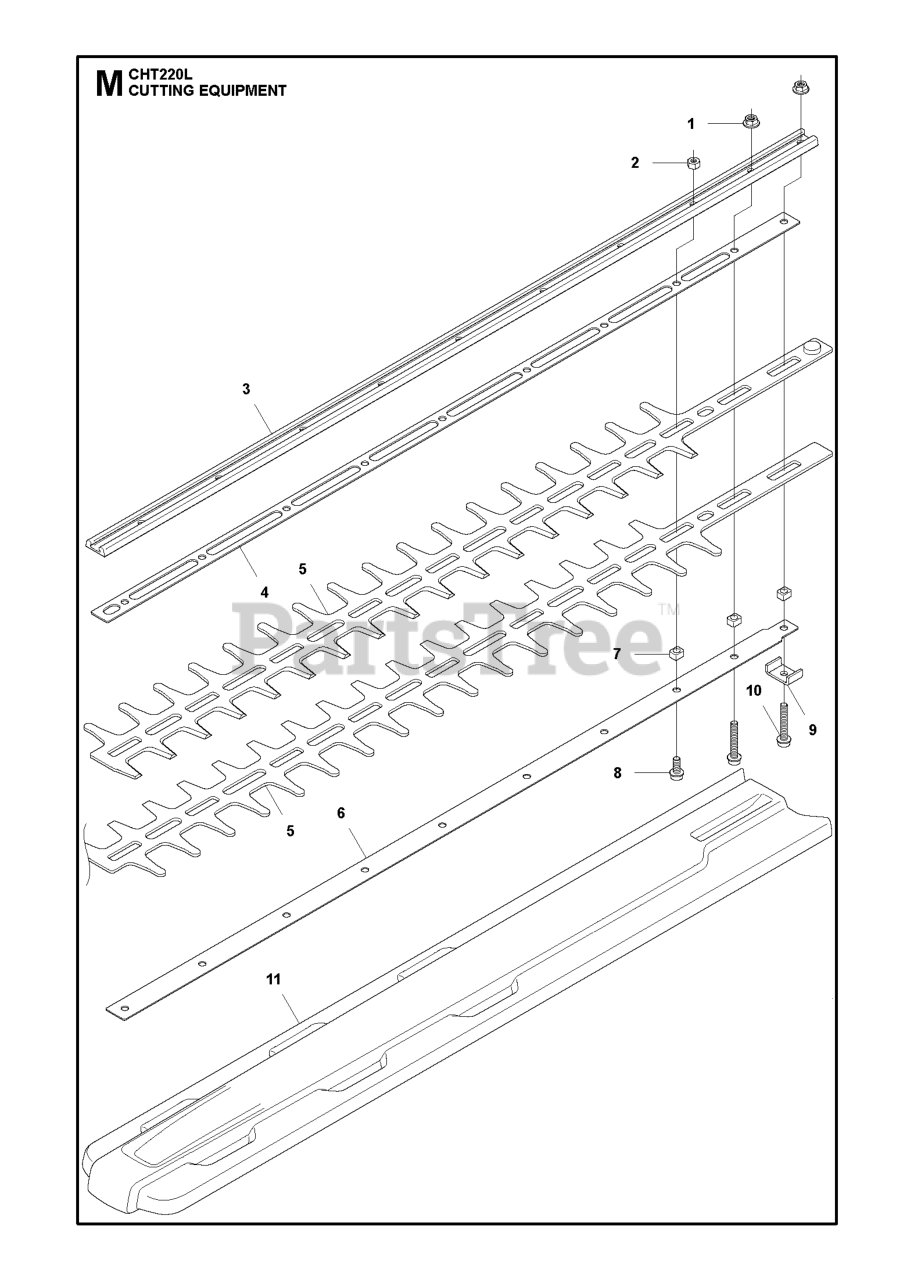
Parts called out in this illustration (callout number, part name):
4	WEAR PLATE
5	BLADE HEDGE TRIMMER
11	TRANSPORT GUARD
